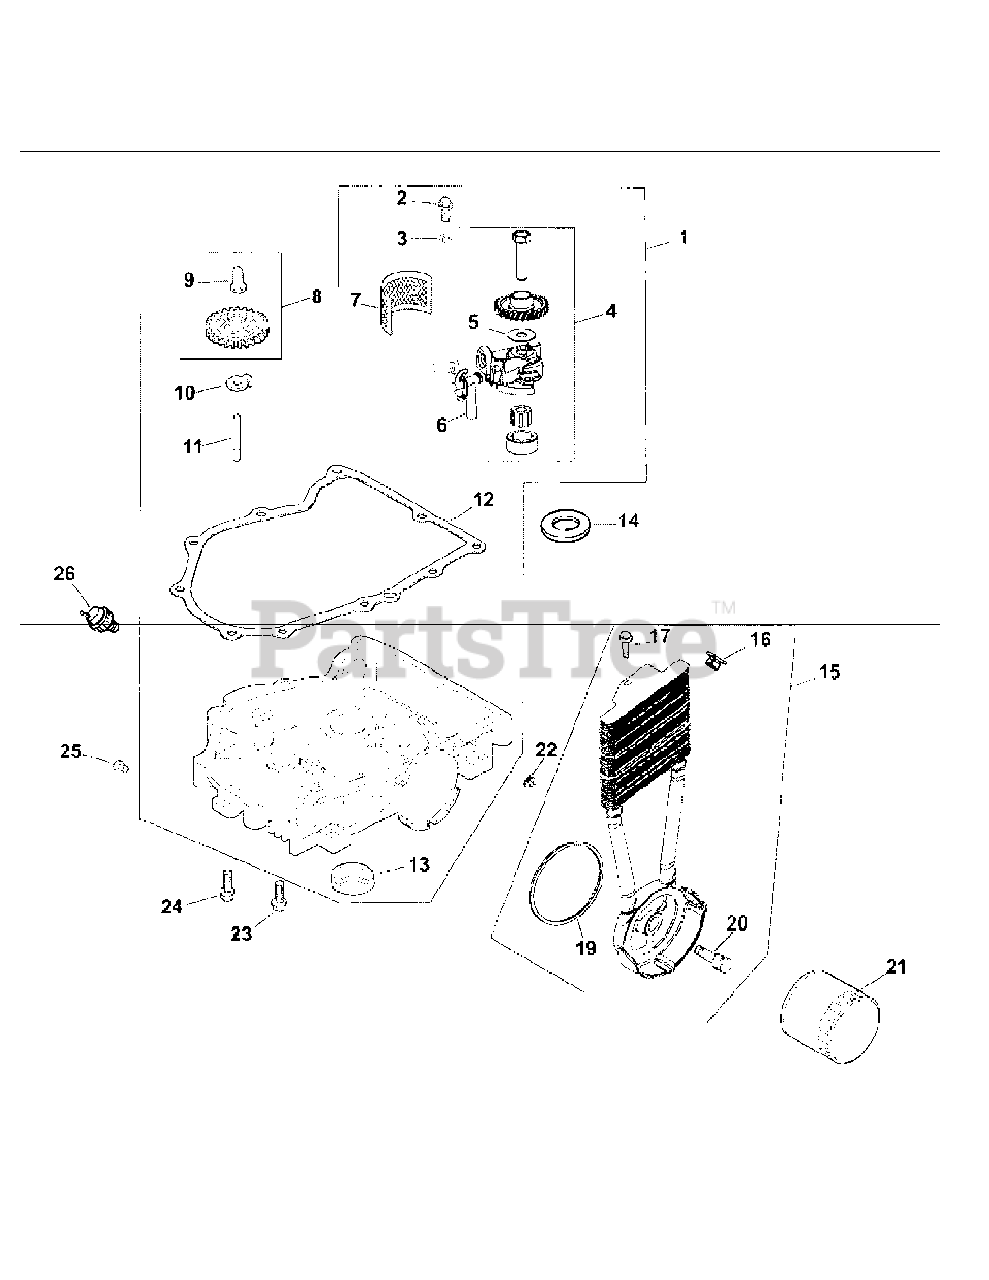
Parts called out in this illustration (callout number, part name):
1	Oil Pan Kit w/Gasket
2	Hex Flange Screw
3	Plain Washer
4	Oil Pump Assembly
5	Oil Pickup Tube O-Ring
6	Oil Pickup Tube
8	Governor Gear Kit
9	Governor Regulating Pin
11	Governor Gear Shaft
12	Oil Pan Gasket
15	Oil Cooler Kit
17	Hex Cap Screw
20	Oil Filter Nipple
23	Hex Flange Screw
24	Hex Flange Screw
25	Hex Head Plug
26	Oil Pressure Switch
